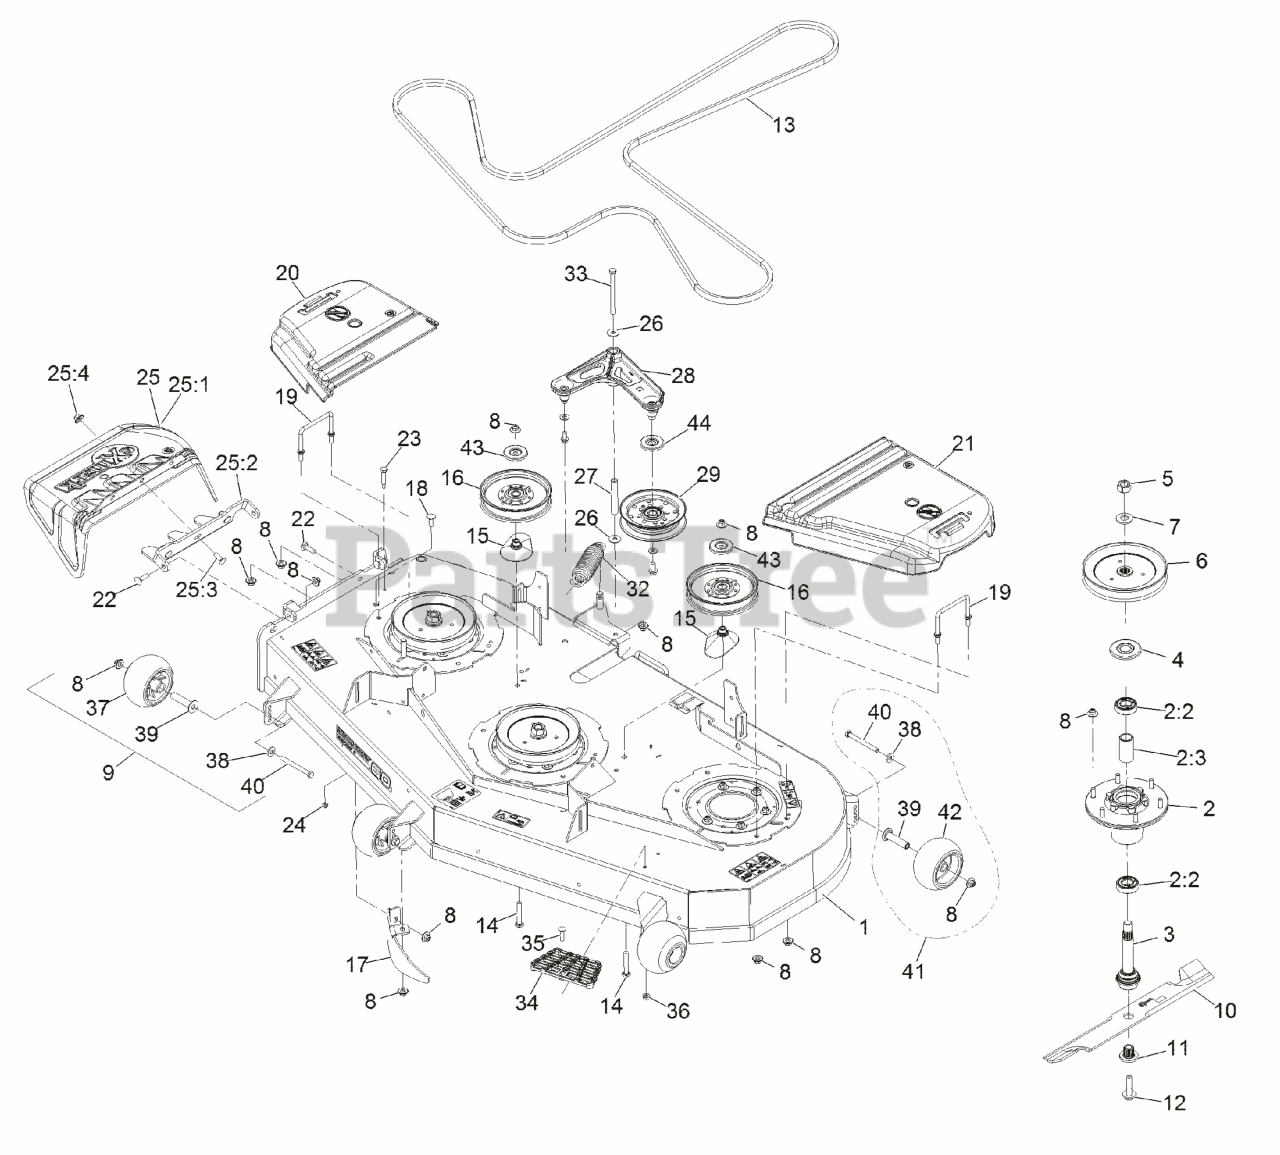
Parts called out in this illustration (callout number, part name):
1	ASM-DECK W/DECALS 604
2	ASM-CUTTER HSG WITH BEARINGS
2:2	BEARING-BALL
2:3	SPACER-BEARING
3	ASM-SPINDLE AND SEAL
4	GUARD,BEARING TOP .989
5	NUT-HEX
6	SHEAVE,BLADE DRIVE 7.25
8	Nut-Nyloc 3/8-16 Flg
9	KIT, ANTI-SCALP ROLLER
10	Blade-Extreme 2, 20.50"
11	BUSHING,SPLINED
12	SCREW,SEMS 1/2-20 X 2.19
13	BELT-V
14	BOLT-CARR, SHORT NECK
15	SPACER-PULLEY
17	DOGLEG - LZ60
18	SCREW-CARR
19	WIREFORM-COVER
20	COVER-BELT, RH
21	COVER-BELT, LH
22	BOLT-CARR
23	BOLT-SHOULDER
25	ASM,DISCHARGE CHUTE
25:1	CHUTE,DISCHARGE
25:2	BRACKET,DISCHARGE CHUTE
25:3	SCREW-CARR
25:4	Nut-Nyloc 3/8-16 Flg
27	BUSHING
28	IDLER ARM ASM
32	SPRING-EXTENSION
33	SCREW-HH
34	STEP-DECK
35	Bolt-Carriage 5/16-18 X 1 1/4
36	NUT-HF, NI
37	ROLLER-SCALP, ANTI
38	WASHER-BELLEVILLE
39	AXLE, ROLLER
40	SCREW-HH 3/8-16 X 3 3/4 GR 8
41	KIT-ANTISCALP ROLLER
42	ROLLER-SCALP, ANTI
